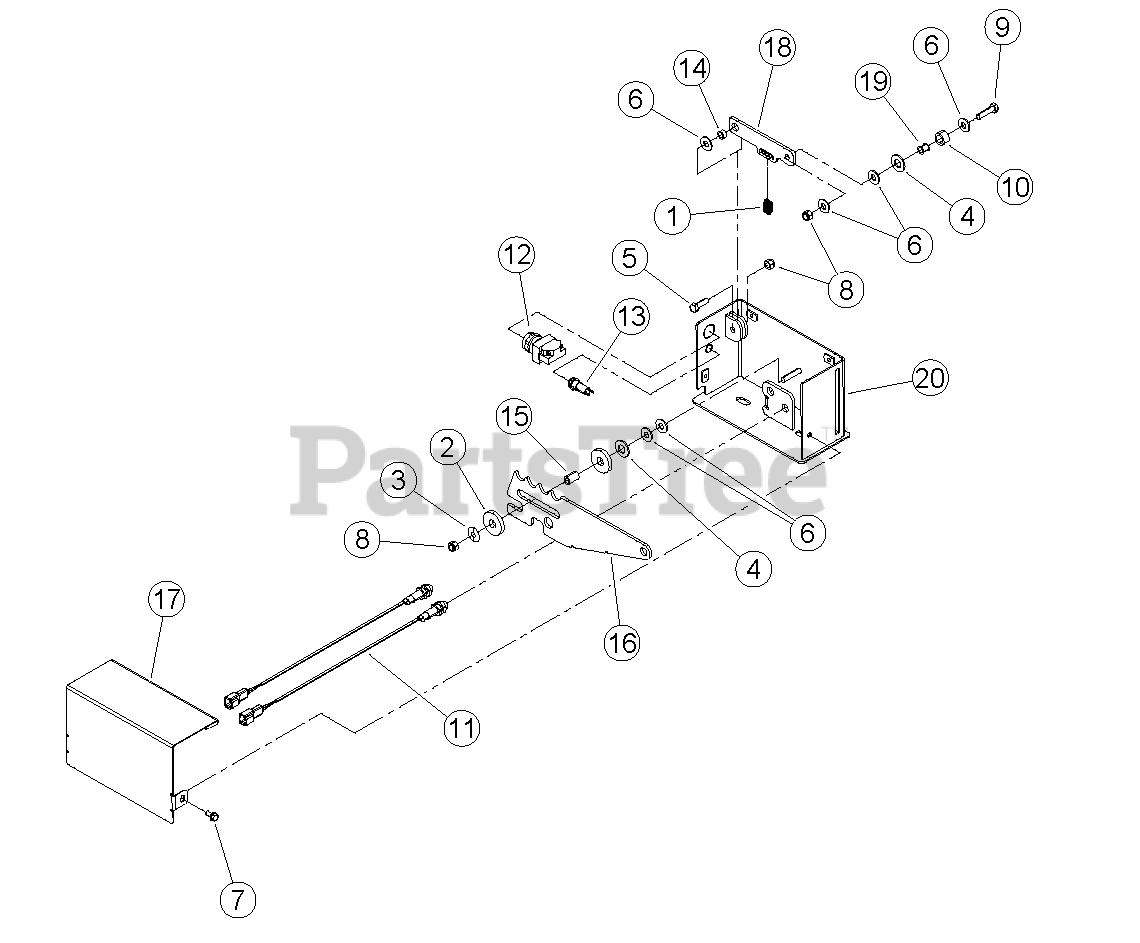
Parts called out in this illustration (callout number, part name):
1	SPRING, CONTROL BAR
2	WASHER, UHMW SPACER .515ID X 1.50OD
3	WASHER, SPRING
4	WASHER, 1/2 SAE FLAT ZP
5	BOLT, 5/16 X 1 HEX GR5 NC ZP
6	WASHER, 5/16 FLAT ZP
7	BOLT, 1/4 X 1/2 SERR FLANGE GR5 ZP
8	NUT, 5/16 NE NYLOCK ZP
9	BOLT, 5/16 X 1-1/4 HEX GR5 NC ZP
10	ROLLER, NYLON .75OD X .502ID X .440
11	SENSOR, M12 PNP PROXIMITY
12	SWITCH, MOMENTARY IP67 NORMALLY OFF
13	LED, TRI-COLOR 12V 3-TERMINAL BASE
14	SPACER, IDLER PIVOT
15	SPACER, .50 X .775
16	BAR, SWITCH CONTROL
18	LINK, DETENT
19	SPACER, 1/2 OD X .35 ID X .47
20	WELDMENT, SWITCH BOX
